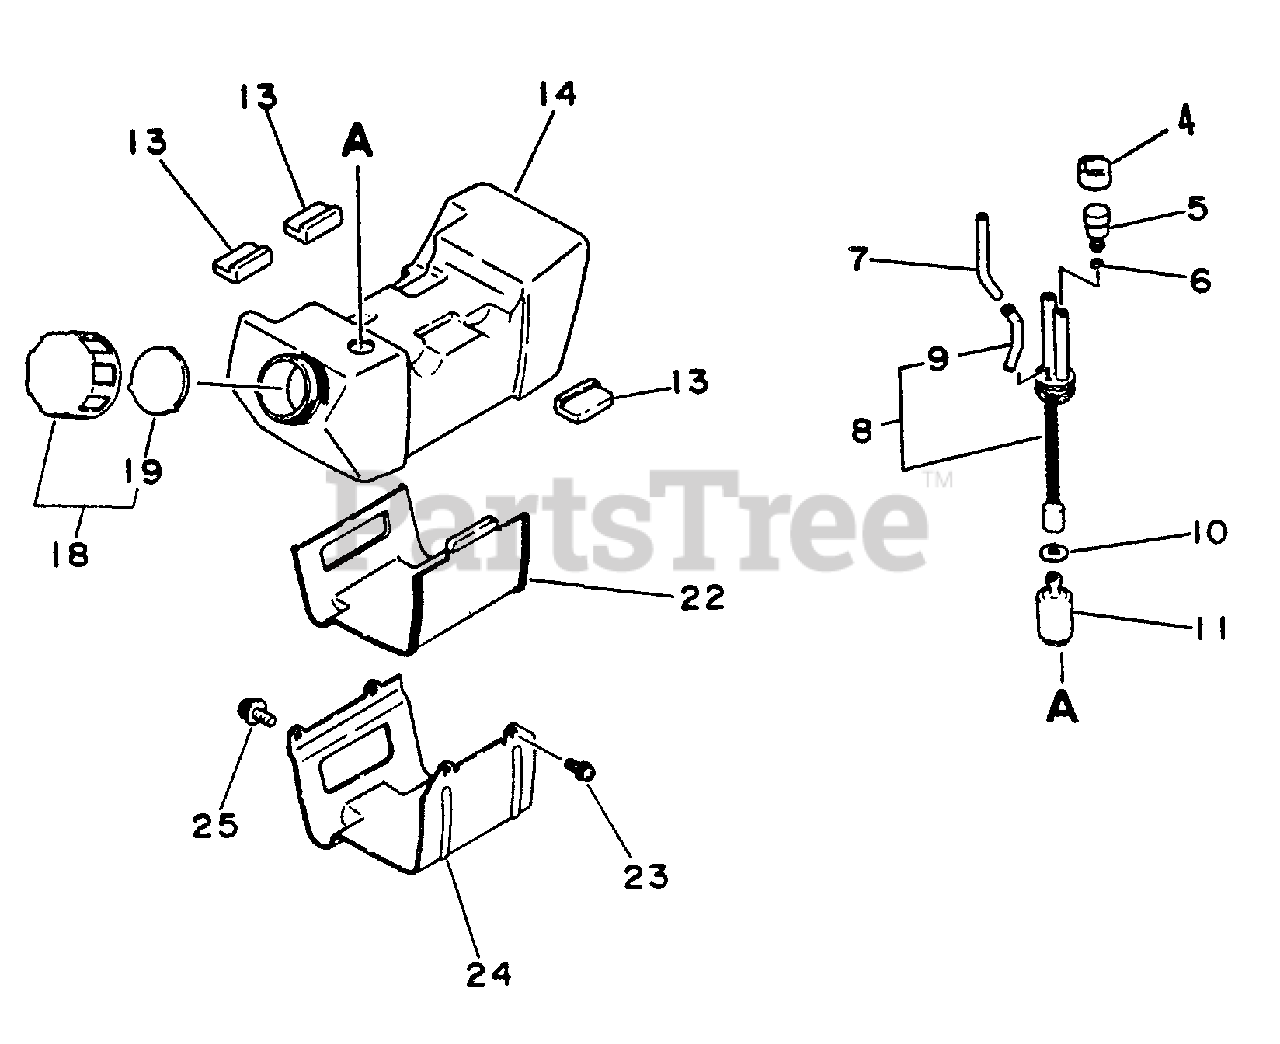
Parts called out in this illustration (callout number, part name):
4	HOLDER, VENT
5	VENT ASSY
7	PIPE, FUEL 3×6×50
8	PIPE, FUEL
9	CONNECTOR, PIPE
10	WASHER 5.5×12×0.8
11	FILTER, FUEL
14	TANK, FUEL
18	CAP ASSY
19	GASKET
23	SCREW 4×10
24	BRACKET, FUEL TANK
25	SCREW 5×12
